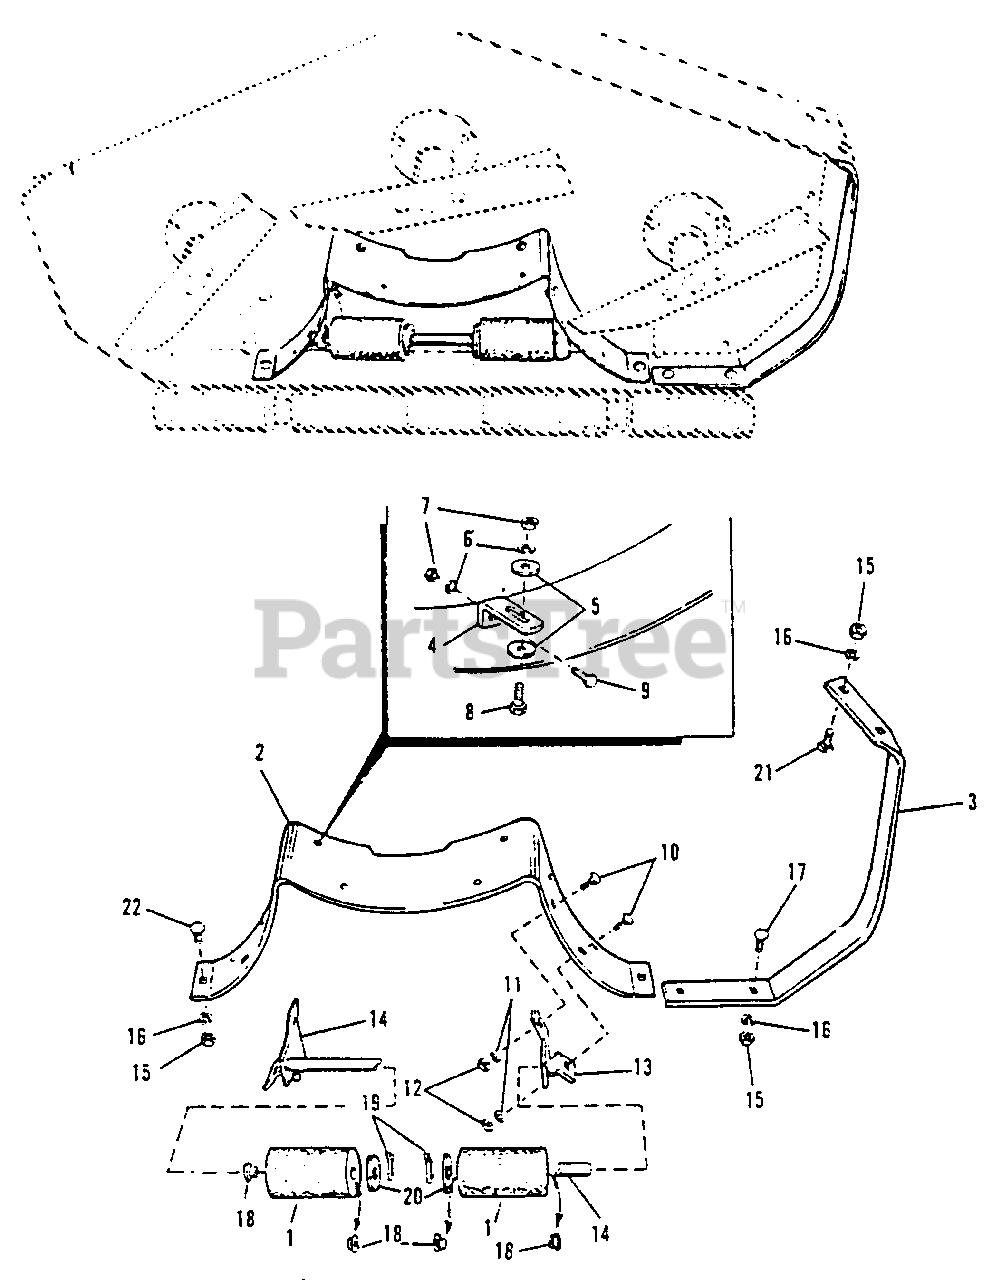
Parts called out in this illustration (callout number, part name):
1	Roller W/Bushing
3	Guard Assembly, Housing
4	Clip Baffle
5	Washer Plain, 1/4"
6	Washer, Lock. 1/4"
7	Nut Hex Full. 1/4"-20 NC
8	Capscrew, Hex. 1/4"-20 x 5/8" lg.
9	Screw Recessed Hex Self Tapping 1/4"-20 NC x 7/8" lg.
10	Bolt, Carriage, 5/16"-18 NC x 3/4" lg.
11	Washer, Lock,. 5/16"
12	Nut, Hex. Full, 5/16"-18 NC
13	Bracket, Roller, Lower, L.H.
14	Bracket & Shaft Assembly
15	Nut, Hex., Full, 3/8"-16 NC
16	Washer, Lock, 3/8"
17	Bolt. Carriage, 3/8"-16 NC x 3/4" lg.
19	Pin, Cotter, 3/16" x 1" lg.
21	Bolt, Carriage, 3/8"-16 NC x 1" lg.
22	Bolt, Carriage, 3/8"-16 x 3/4" lg.
